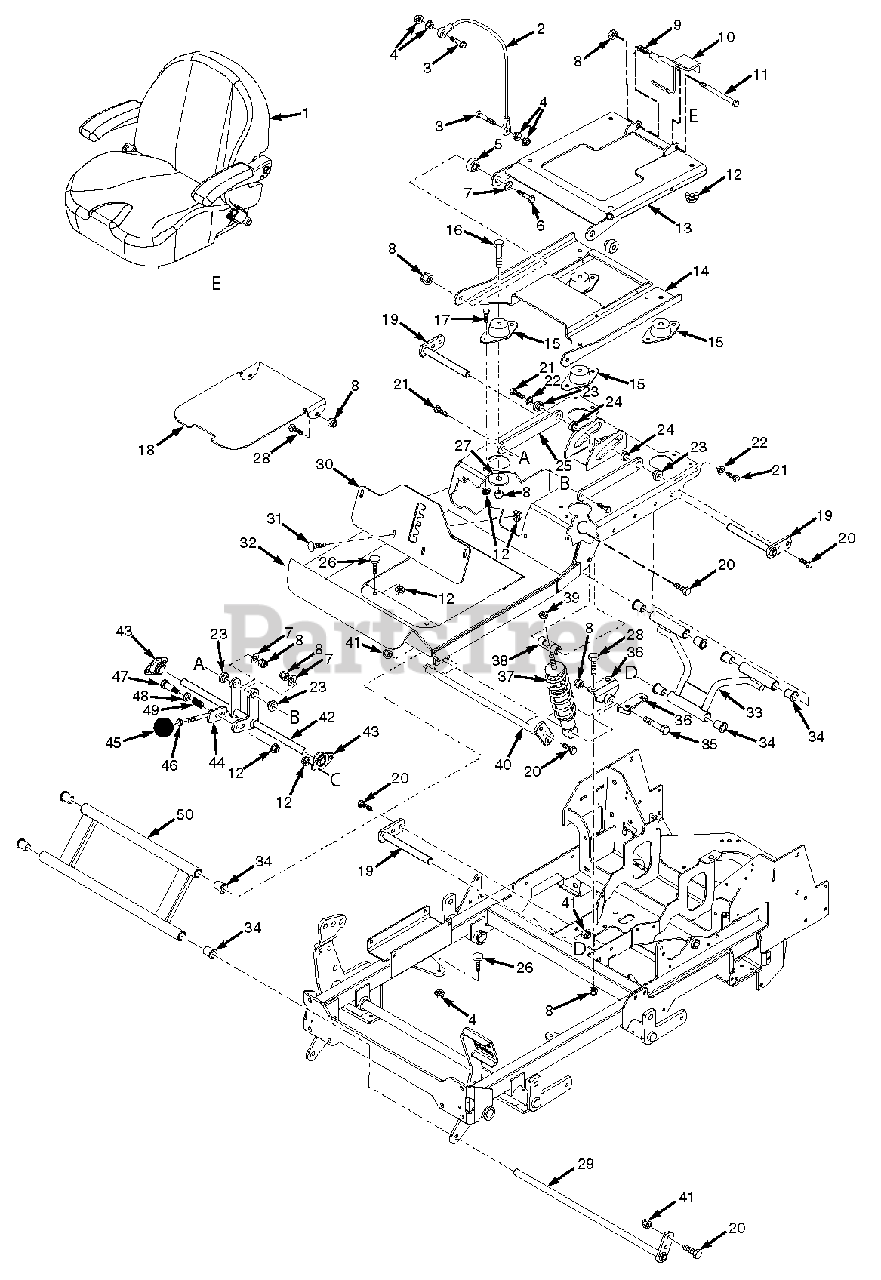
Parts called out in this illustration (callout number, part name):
1	Seat Assembly
2	Cable, Seat Stop
3	Bolt, Hex Head 1/4-20 x 1-1/4"
4	Nut, Serrated Flange 1/4-20
5	Sleeve, Seat Base Mount
6	Bolt, Hex Head 3/8-16 x 2"
7	Flatwasher, 3/8-.391 x .938 x .105
8	Nut, Elastic Stop 3/8-16
9	Spring, Seat Latch
10	Latch Weldment, Seat
11	Bolt, Hex Head 3/8-16 x 6"
12	Nut, Serrated Flange 5/16-18
13	Seat Plate Weldment
14	Seat Mounting Plate Weldment w/Decal
15	Isolator, Seat
16	Bolt, Hex Head 3/8-16 x 2-1/4"
17	Bolt, Hex Head 5/16-18 x 3/4"
18	Cover, Foot Plate
19	Shaft Weldment, Rear Op. Platform Pivot
20	Bolt, Hex Head 5/16-18 x 1"
21	Bolt, Hex Head 3/8-16 x 1-1/2"
22	Lockwasher, 3/8" Spring
23	Bushing
24	Bearing
25	Link, Suspension Seat Tensioner
26	Bumper, Rubber
27	Flatwasher, 3/8-.406 x 2.25 x .188
28	Bolt, Hex Head 3/8-16 x 1"
29	Pin Weldment, Op Platform Lower Pivot
30	Bracket, Suspension Adjustment w/Decal
31	Bolt, Carriage 5/16-18 x 1"
32	Seat Mounting Base Weldment w/Decal
33	Suspension Pivot Assembly, Rear
34	Bearing
35	Bolt, Hex Head 3/8-16 x 2-3/4"
36	Mount Weldment, Shock
37	Shock Absorber, Suspension
38	Mount, Suspension Shock
39	Nut, Elastic Stop 3/8-24 Grade 8
40	Pin Weldment, Op Platform Upper Pivot
41	Nut, Elastic Stop 5/16-18
42	Pivot Weldment, Suspension Tensioner
43	Bearing, Self Align 5/8" ID
44	Adjustment Lever, Suspension
46	Nut, Jam 3/8-16
47	Bolt, Shoulder 3/8 x 1"
47	Bolt, Shoulder 3/8 x 3/8"
48	Flatwasher, 3/8-.406 x .812 x .065
49	Spring
50	Suspension Pivot Assembly, Front
